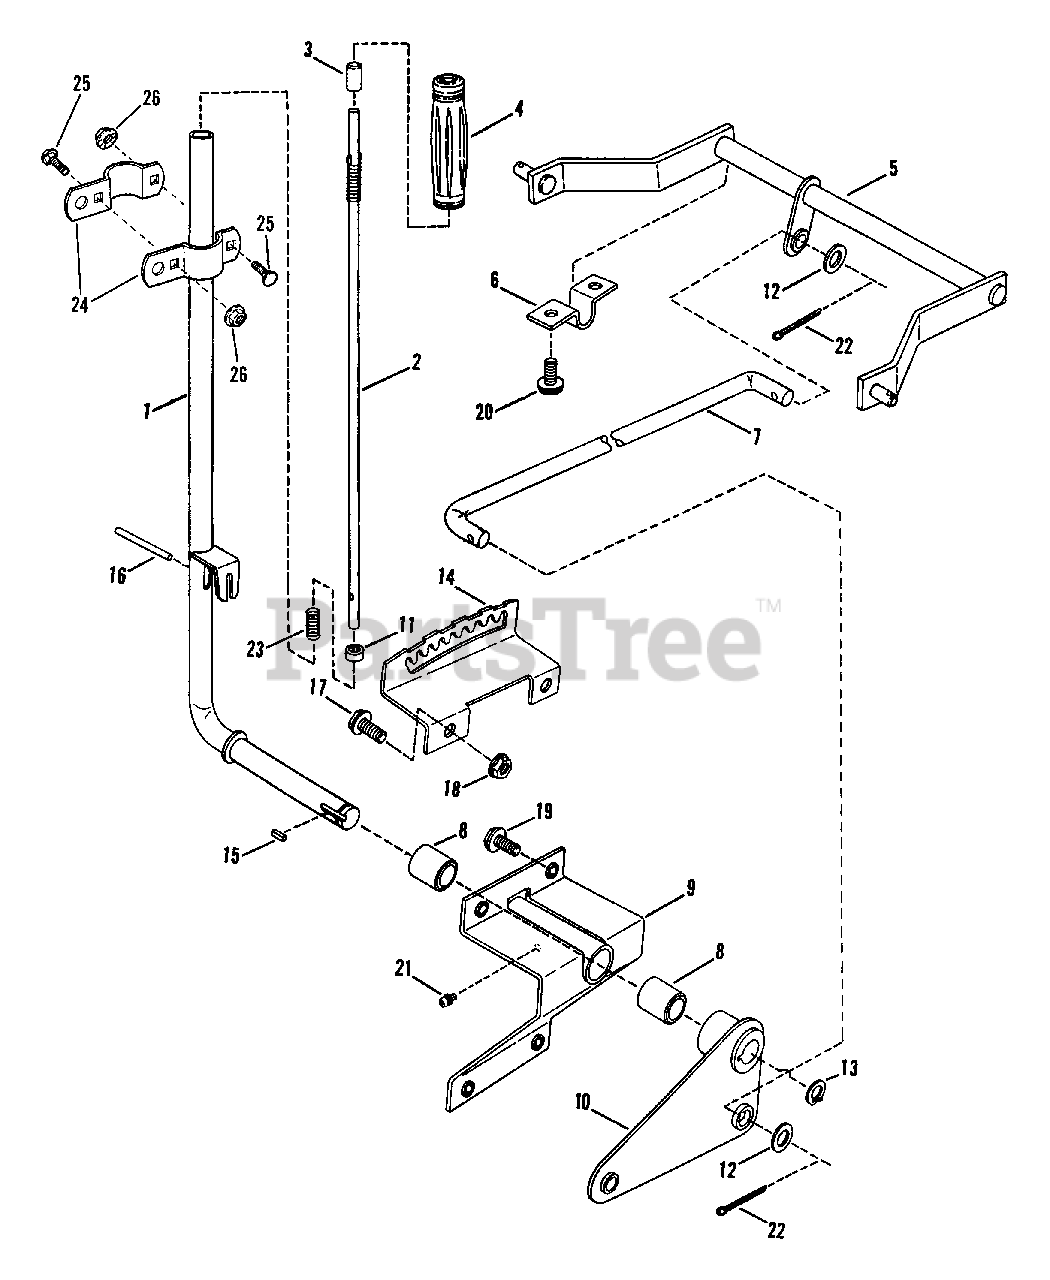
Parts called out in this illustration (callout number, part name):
1	ARM, Implement Lift Lever
2	ROD, Lift Lever
3	CAP, Lift Release
4	GRIP, Handle
5	ARM, Rear Lift (1985)(22")
6	BRACKET, Hanger
7	LIFT-ROD
8	BEARING, Sleeve
9	PIVOT ASSY, Lift Lever
10	LEVER-ARM
11	PLUG, Rod
12	WASHER, 1/2 SAE
13	RING, 7/8 Ext. Retaining
14	QUADRANT, Lift Lever
15	KEY, 1/4 x 1/4 Square
16	PIN, 3/16 x 2" Groove
17	BOLT, 3/8-16 x 3/4" Hex Flange Lock
18	NUT, 3/8-16 Hex Flange Lock
19	SCREW, 5/16-18 x 5/8" Hex Washer Face Self-Tap
20	SCREW, 3/8-16 x 1/2" Hex Washer Face Self-Tap
21	LUBE FITTING, Straight (press-fit for .187 dia. Hole)
22	PIN, 1/8 x 1" Cotter
23	SPRING, Lift Handle
24	TAB
25	BOLT, 1/4-20 x 1/2" Short Neck Carriage, Grade 5
26	NUT, 1/4-20 Hex Flange Lock
